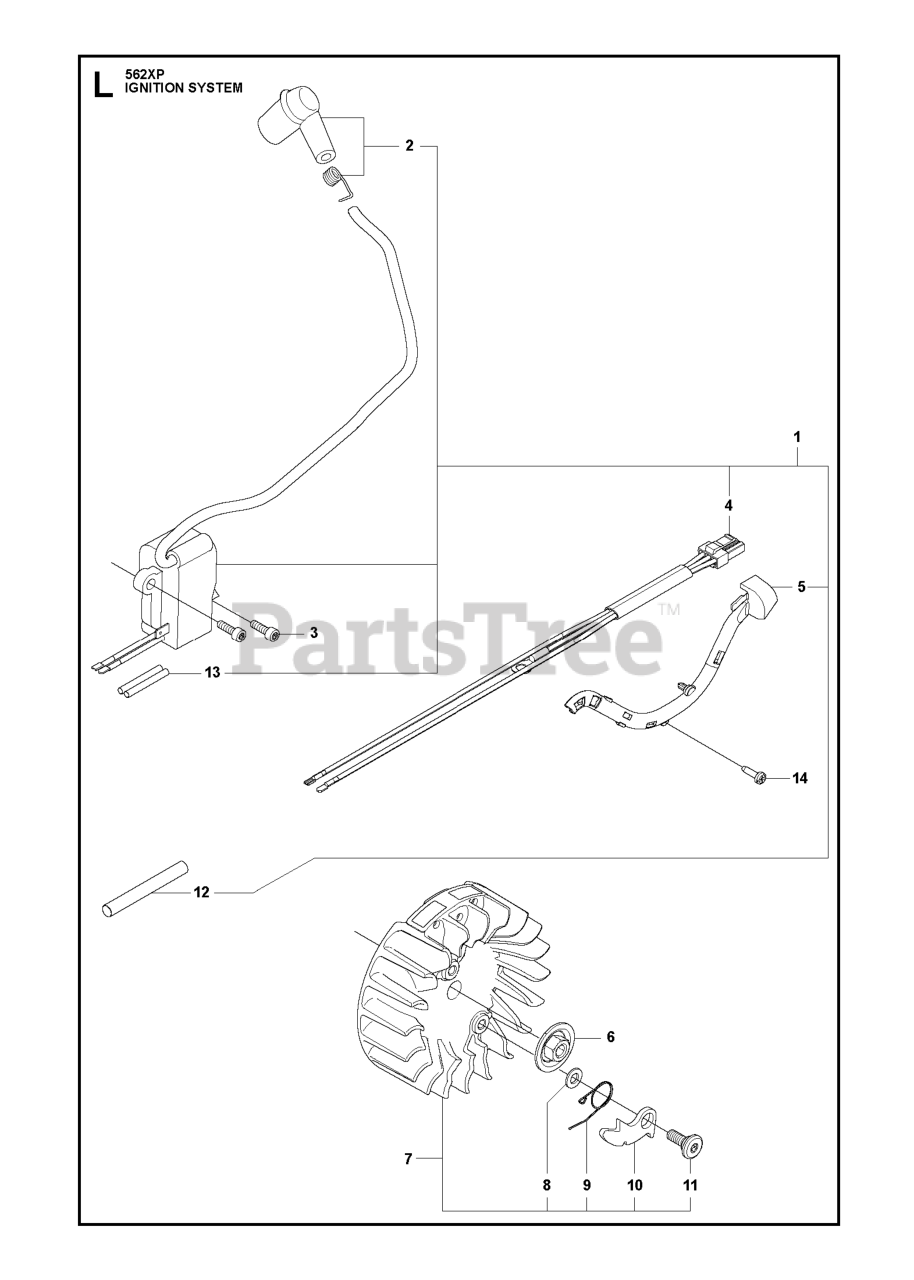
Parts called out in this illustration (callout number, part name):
1	IGNITION MODULE ASSY
2	SPARK PLUG CAP ASSY
3	SCREW ITXSCFM
4	WIRING ASSY
5	CABLE HOLDER
6	NUT,M8X1PP A/F13X6,8XØ30X4X1,5
7	FLYWHEEL ASSY
11	SCREW
12	CABLE COVER
13	SHRINK HOSE
14	SCREW CITXPANT
